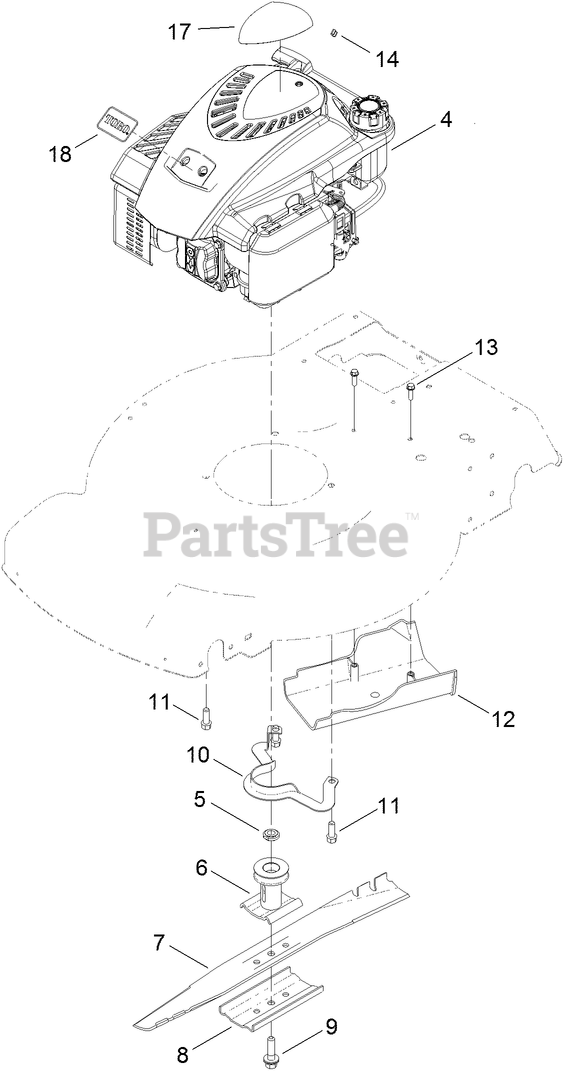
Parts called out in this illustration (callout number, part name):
5	SPACER-DRIVER
6	DRIVER-BLADE
8	SUPPORT-BLADE
10	GUIDE-BELT
11	SCREW-TAPTITE
12	COVER-BELT
13	SCREW-HWH
14	STOP-ROPE
17	DECAL-SHROUD
